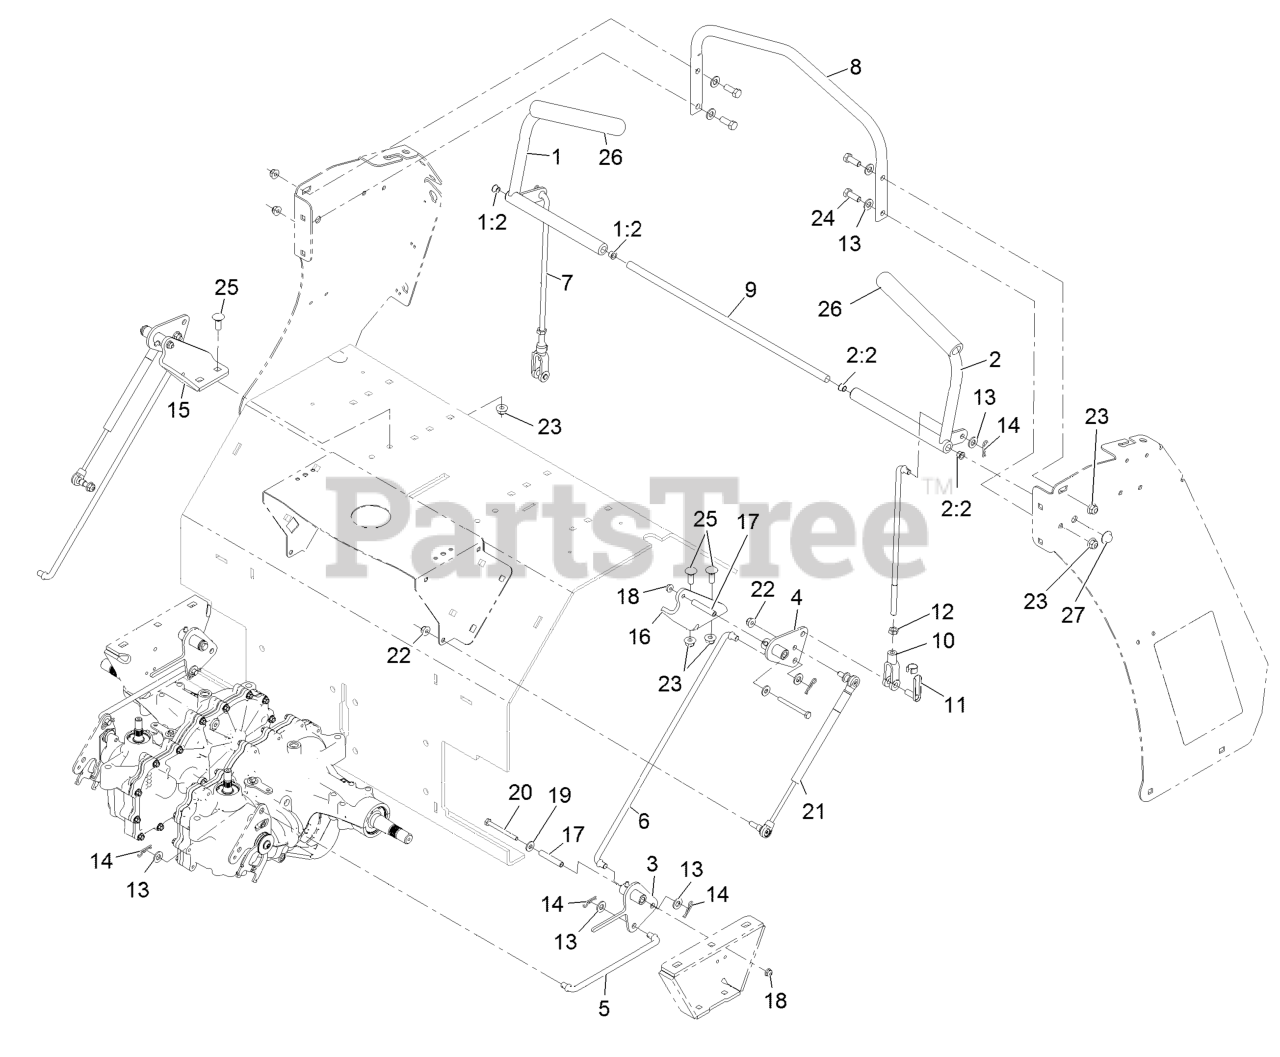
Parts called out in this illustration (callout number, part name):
1	RH CONTROL HANDLE ASM
1:2	BEARING-FLANGE
2	LH CONTROL HANDLE ASM
2:2	BEARING-FLANGE
3	BELLCRANK (W/ARM)
4	Bellcrank-W/Arm [Black]
5	LINK-CONTROL, HYDRO
6	LINK-BELLCRANK CONTROL
7	LINK-CONTROL, BELL CRANK
8	BAR-REFERENCE
9	SHAFT-PIVOT, CONTROL
10	YOKE-LINKAGE, BRAKE
11	PIN-SPRING, CLEVIS
12	NUT-HEX
13	WASHER-FLAT
14	PIN-COTTER
15	BRACKET-PIVOT, RH
16	BRACKET-PIVOT, LH
19	WASHER-FLAT
20	SCREW-HH
21	DAMPER-CONTROL, MOTION
22	NUT-HF, NI
23	NUT-HF, NI
24	SCREW-HH
25	BOLT-CARR
26	GRIP-LEVER, CONTROL
27	NUT-PUSH
